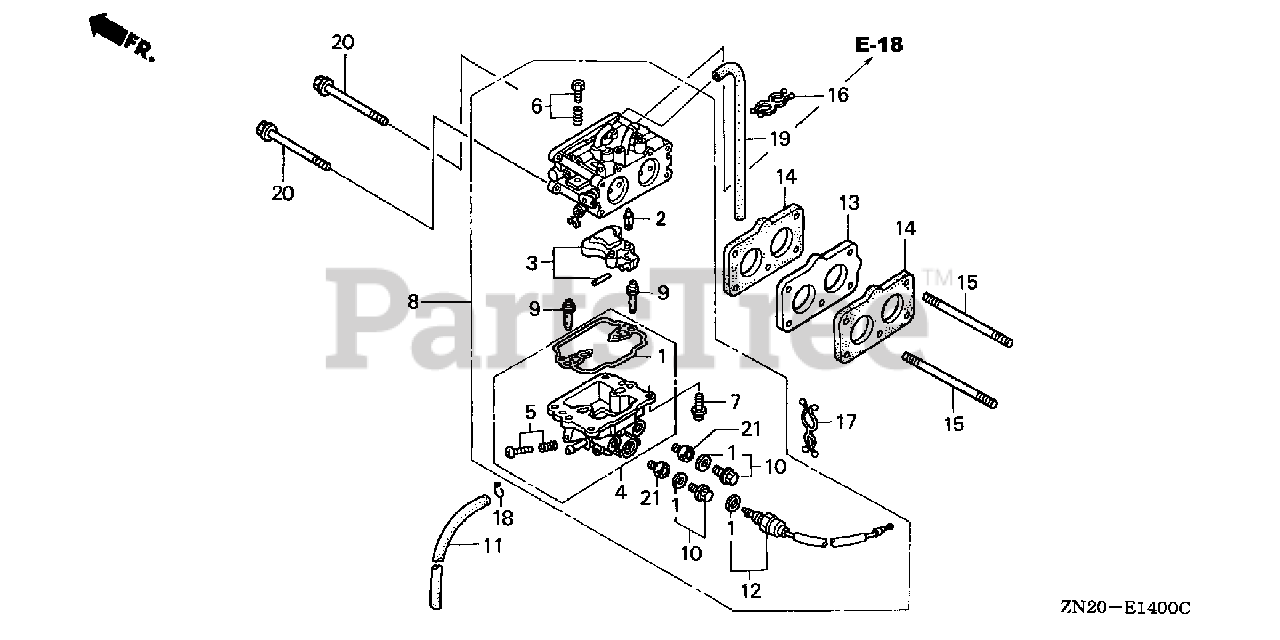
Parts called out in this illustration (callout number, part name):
1	GASKET SET
2	VALVE, FLOAT
3	FLOAT SET
4	CHAMBER SET, FLOAT
5	SCREW SET, DRAIN
6	SCREW SET
7	SCREW-WASHER
8	CARBURETOR ASSY. (TB02AA)
9	JET, SLOW (#54)
10	PLUG SET
11	TUBE, DRAIN
12	VALVE ASSY., SOLENOID
13	INSULATOR, CARBURETOR
14	GASKET, CARBURETOR
15	BOLT, STUD (6X108)
16	CLIP, WIRE HARNESS
17	CLIP, PURSE LOCK
18	CLIP, TUBE (B8)
19	BULK HOSE, VACUUM (4.5X1000) (4.5X540)
20	BOLT, FLANGE (6X95)
21	JET, MAIN (#104)
21	JET, MAIN (#108)
21	JET, MAIN (#112)
